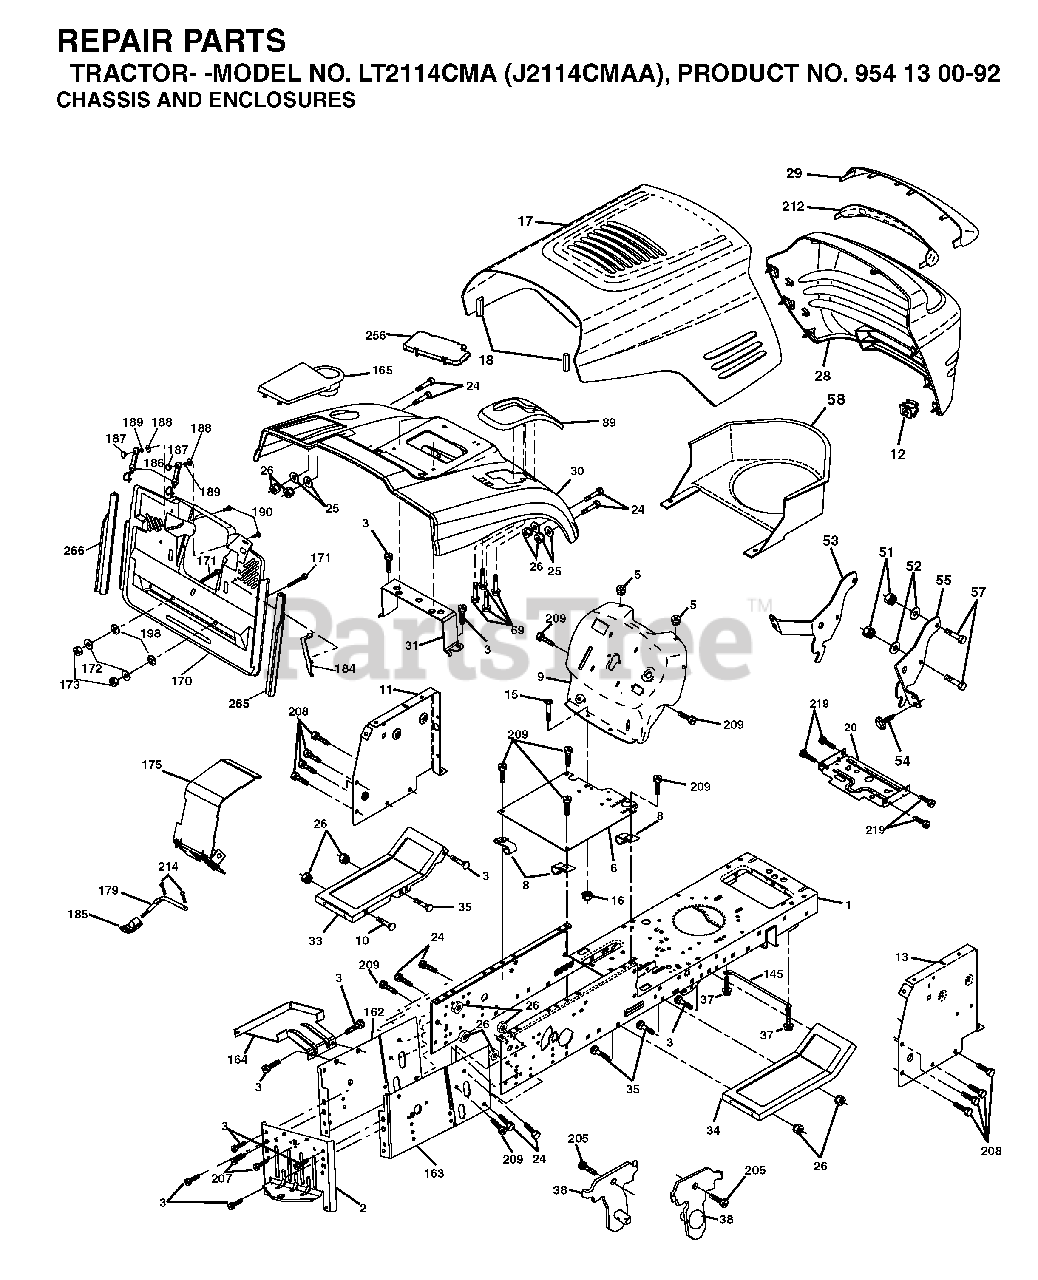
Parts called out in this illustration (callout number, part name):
1	CHASSIS
3	SCREW 3/8-16X3/4
5	BUMPER.RUBBER.HOOD
8	CLIP,INSULATOR
10	BOLT D
11	PANEL.DASH.LH.LTX
13	PANEL ASM, DASH RH
16	NUT
18	BUMPER.HOOD.LARGE.1.75"
20	PLATE MTG.BATTERY/FUEL TANK
25	WASHER
26	NUT
31	BRACKET SUPPORT FENDER
51	LOCKNUT
57	BOLT
58	AIR DUCT P/L/LT
69	SCREW.HI-LO.CONSOLE
145	ROD PIVOT CHASSIS/HOOD
164	SUPPORT
171	BOLT
172	WASHER
186	LATCH ASSY
187	WELDNUT
189	LOCKWASHER
207	SCREW, 5/16-18 X 1/2
208	SCREW 3/8-16X1/2
209	SCREW, 3/8-16X3/4
214	RETAINER M
219	SCREW
